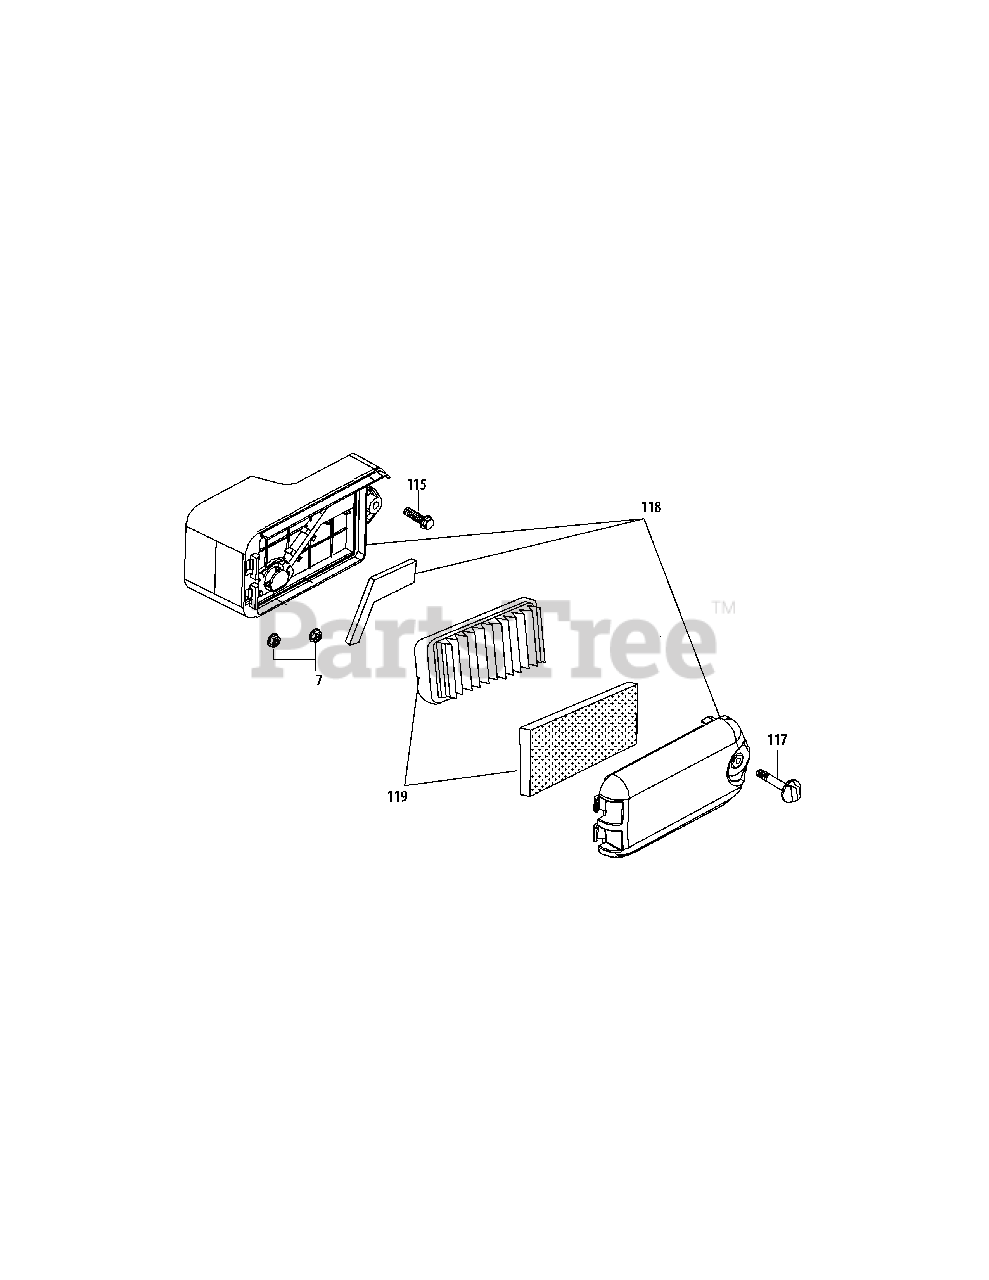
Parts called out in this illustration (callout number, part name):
7	Nut M6 X 10 Mm
115	Flange Bolt M 6 X 30
117	Air Cleaner Thumb Screw
118	Air Cleaner Housing Assy Comp
119	Air Cleaner Kit
